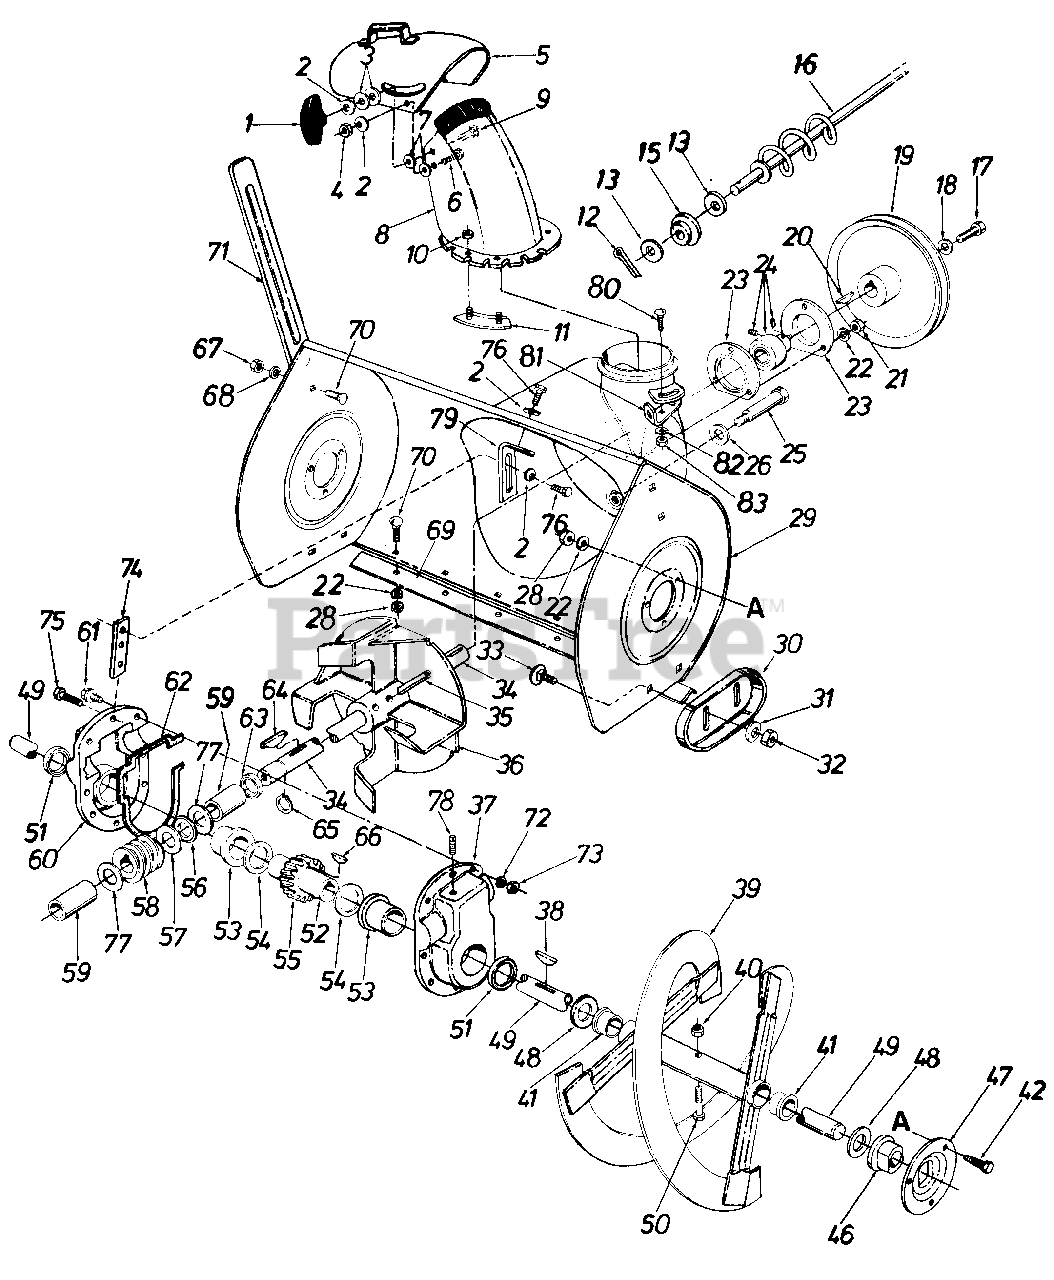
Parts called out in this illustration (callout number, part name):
1	Hand Knob Ass'y.
2	Bell-Wash. .345 I.D. x .88 O.D. x .060
4	Hex Cent. L-Nut 5/16-18 Thd.
5	Top Chute Ass'y.
6	Carr. Bolt 5/16-18 x .62" Lg.
8	Chute Ass'y.
9	Carr. Bolt 5/16-18 x 1.00" Lg.
10	Hex Cent. L-Nut 1/2-20 Thd.
11	Chute Flange Keeper Ass'y.
12	Cotter Pin
13	Fl-Wash. .385" I.D. x .62" O.D.
15	Bushing
16	Chute Crank Ass'y.
17	Hex L-Scr. 5/16-18 x .88" Lg.
18	Bell-Wash. .345 I.D. x .88 O.D. x .060
19	V-Pulley .875 I.D. x 10.12 O.D.
20	#9 Hi-Pro Key 3/16 x 3/4" Dia.
21	Hex Nut 5/16-18 Thd.*
22	L-Wash. 5/16" Scr.*
23	Bearing Hsg.-Self Aligning Brg.
24	Self Aligning Brg. .875 I.D.
25	Stud 3/8-16 x 2.75" Lg.
26	Bell-Wash. .400 I.D. x .88 O.D. x .060
28	Hex Nut 5/16-18 Thd.*
29	Blower Hsg. Ass'y.
30	Slide Shoe
31	Bell-Wash. .400 I.D. x .88 O.D. x .060
32	Hex Jam Nut 3/8-16 Thd.
33	Carr. Bolt 3/8-16 x .62" Lg.
34	Blower Axle
35	Spring Pin Spiral 5/16" Dia. x 1.75" Lg.
38	#91 Woodruff Key 1/4" X 3/4" Dia.
41	Plastic Bushing
42	Hex Sems Scr. 5/16-18 x .75" Lg. *
46	Flange Brg. w/Flats 1.0" I.D.
47	Bearing Hsg.-Spiral Hsg.
48	Fl-Wash. 1.06 I.D. x 1.75" O.D. x .100
49	Spiral Axle-26"
50	Hex Bolt 5/16-18 x 1.75" Lg.
51	Oil Seal 1.50" I.D.
52	Worm Gear Shaft
53	Flange Brg. 1.503 I.D.
54	Fl-Wash. 1.50 I.D. x 2.00 O.D x .030
55	Double Threaded Worm Gear
56	Thrust Brg. .88 I.D. x 1.44 O.D. x .078
57	Fl-Wash. .88 I.D. x 1.40 O.D. x .1 50
58	Double Threaded Worm- L.H.
59	Sleeve Brg. .875 I.D.
60	Complete Gear Hsg. Half- R.H. (Incl. Ref. Nos. 51 & 53)
61	Hex Scr. 5/16-18 x 1.00" Lg.
62	Gasket
63	Oil Seal .875" I.D.
64	#9 Hi-Pro Key 3/16 x 3/4" Dia.
65	Snap Ring for .875" Dia. Shaft
66	#91 Woodruff Key 1/4 X 3/4" Dia.
67	Hex Nut 5/16-18 Thd.*
68	L-Wash. 5/16" Scr.*
70	Carr. Bolt 5/16-18 x .62" Lg.
71	Drift Cutter
72	Wave Wash. 5/16" I.D.*
73	Hex Ins. L-Nut 5/16-18 Thd.
74	Gear Hsg. Support Plate
75	Hex Scr. 5/16-18 x 1.25" Lg.
76	Hex Wash. Hd. Self-Tap Scr. 5/16-18 x .75" Lg.
77	Fl-Wash. .88 I.D. x 1.40 O.D. x .1 50
78	Filler Plug
80	Carr. Bolt 5/16-18 x .75" Lg.*
82	Bell-Wash. .345 I.D. x .88" O.D.
83	Hex Nut 5/16-18 Thd.
